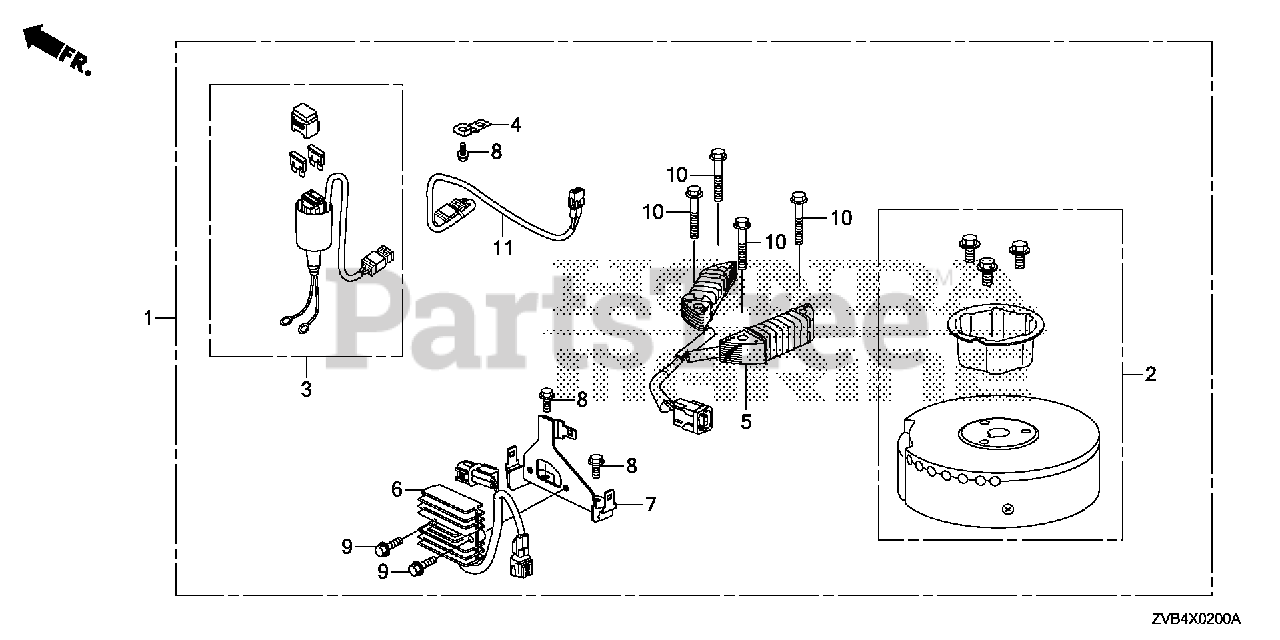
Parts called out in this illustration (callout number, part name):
1	RECEPTACLE KIT, CHARGE *BLACK* (BLACK)
2	FLYWHEEL *BLACK* (CHARGE) (BLACK)
3	HARNESS ASSY., BATTERY
4	BRACKET, BATTERY CABLE
5	COIL ASSY., CHARGE (6A)
6	RECTIFIRE ASSY., REGULATOR
7	BRACKET, REGULATOR
8	BOLT, FLANGE (6X14) (CT200)
9	BOLT, FLANGE (6X20)
10	BOLT, FLANGE (6X32)
11	RECEPTACLE ASSY., CHARGE
